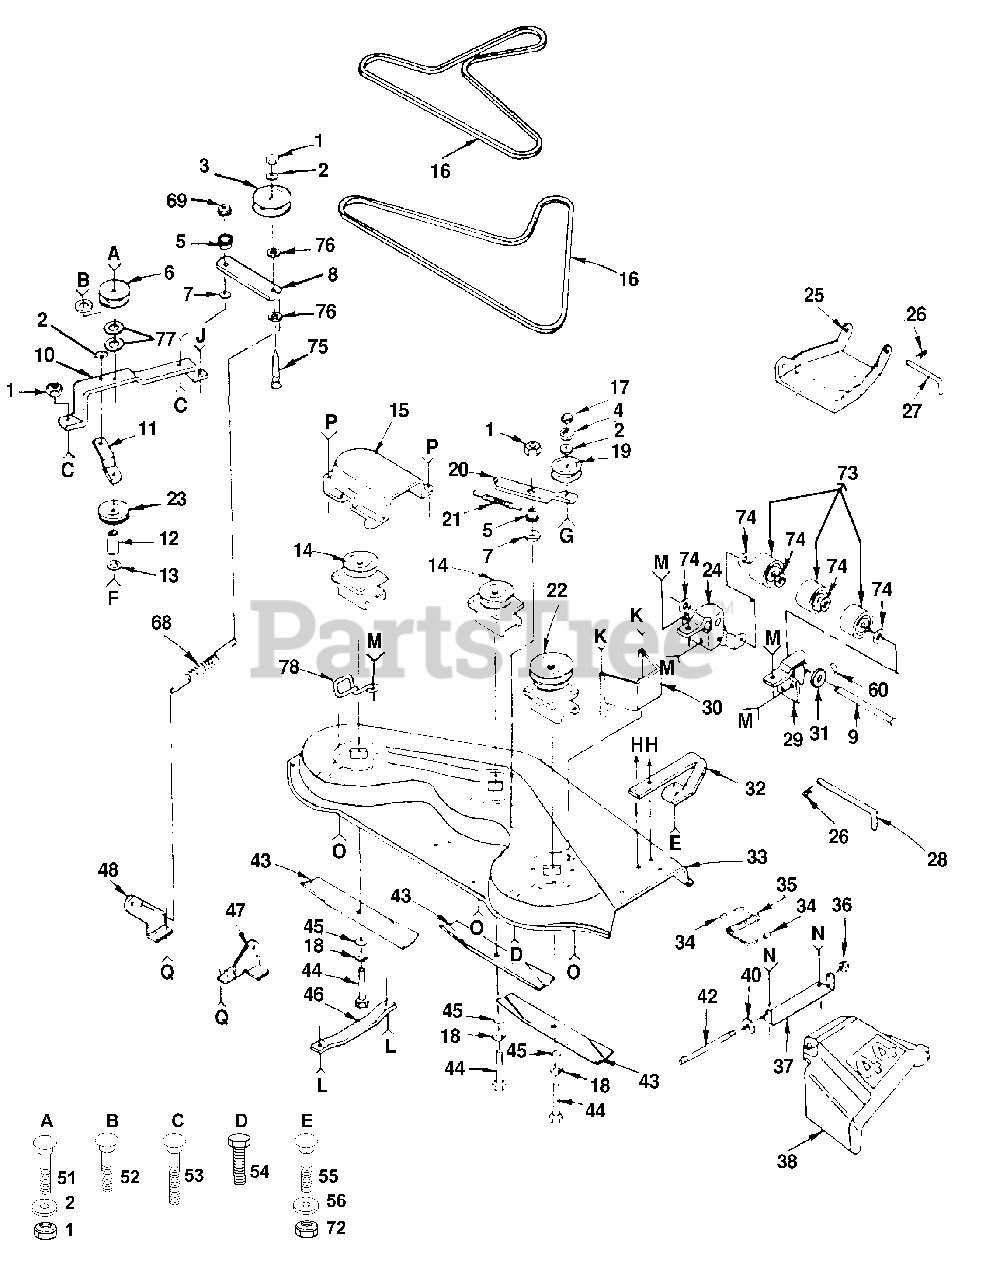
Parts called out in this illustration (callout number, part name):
1	Locknut 3/8-16
2	Washer 13/32 x 1 x 14 Gauge
3	Pulley, Idler
4	Washer, Lock 3/8
6	Pulley, Idler
7	Washer, Wear
8	Arm, Idler
9	Pin, Pivot
10	Bar, Support, Idler
11	Brace, Idler, Deck
13	Washer 13/32 x 13/16 x 16 Gauge
14	Mandrel, Secondary
17	Nut, Hex 3/8-16
18	Washer, Lock 3/8
19	Idler, Flat
20	Arm, Idler, Deck
21	Spring, Extension
22	Mandrel, Primary
23	Pulley, Idler
24	Bracket, Lift, L.H.
25	Link, Parallel
26	Retainer, Spring
27	Pin, Front Hinge
28	Pin, Rear Hinge
29	Bracket, Lift, L.H.
30	Guard, Belt, R.H.
31	Washer 15/32 x 1 x 16 Gauge
32	Runner, R.H.
33	Housing, Mower
34	Cap, Sleeve
35	Spring
37	Bracket, Deflector
38	Guard, Discharge
40	Washer 11/32 x 5/8 x 16 Gauge
42	Rod, Hinge
43	Blade, Mower
44	Bolt, Hex 3/8-24 x 1-1/2 Grade 5
45	Washer 13/32 x 1-1/4 x 12 Gauge
46	Runner, L.H.
47	Bracket, Suspension, Rear, R.H.
48	Bracket, Suspension, Rear, L.H.
51	Bolt, Carriage 3/8-16 x 1-3/4
52	Bolt, Carriage 3/8-16 x 1
53	Bolt, Carriage 3/8-16 x 1-1/2
54	Bolt, Hex 3/8-16 x 1-1/4
55	Bolt, Carriage 5/16-18 x 3/4
56	Washer 11/32 x 11/16 x 16 Gauge
60	Pin, Cotter
68	Spring, Extension
69	Nut, Centerlock 3/8-16
72	Locknut 5/16-18
73	Roller, Nose
74	Washer 15/32 x 1 x 10 Gauge
75	Bolt, Carriage 3/8-16 x 2-1/2
76	Washer 13/32 x 3/4 x 10 Gauge
77	Washer 13/32 x 7/8 x 10 Gauge
78	Keeper, L.H., Mandrel
